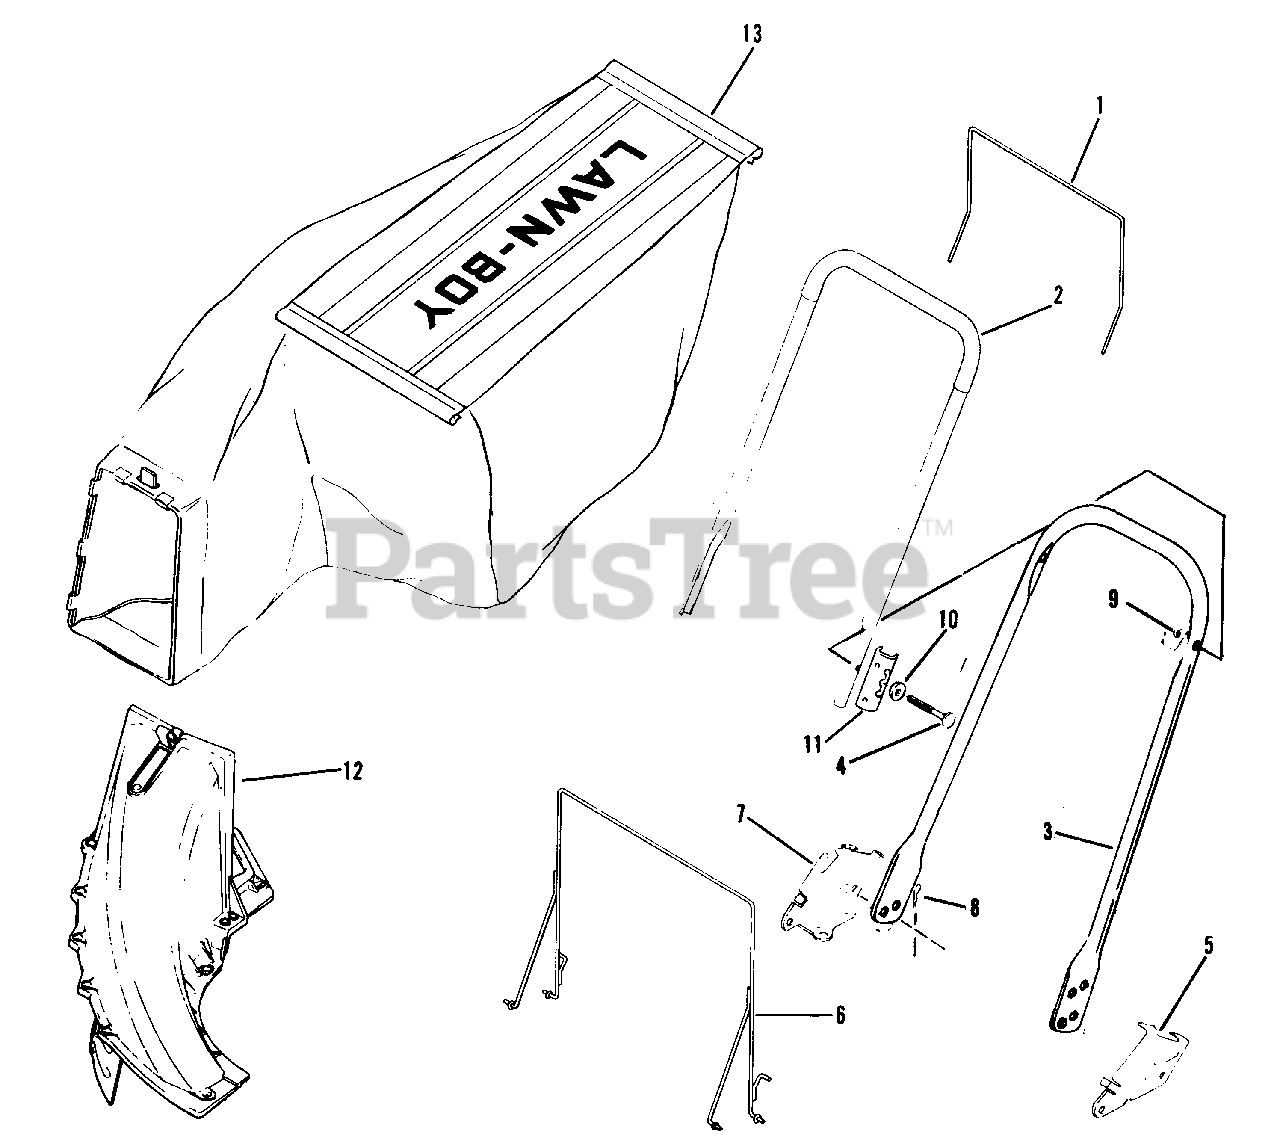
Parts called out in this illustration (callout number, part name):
1	Hanger-Rear
2	Top Handle & Grip Assembly
3	Handle Section-Bottom
4	Screw
5	Handle Bracket-L.H.
6	Hanger Assembly-Front
7	Handle Bracket-R.H.
8	Hair Pin
9	Knob
10	Washer-Curved
11	Bracket-Rear Hanger
12	Chute Assembly
13	Bag & Deflector Assembly
